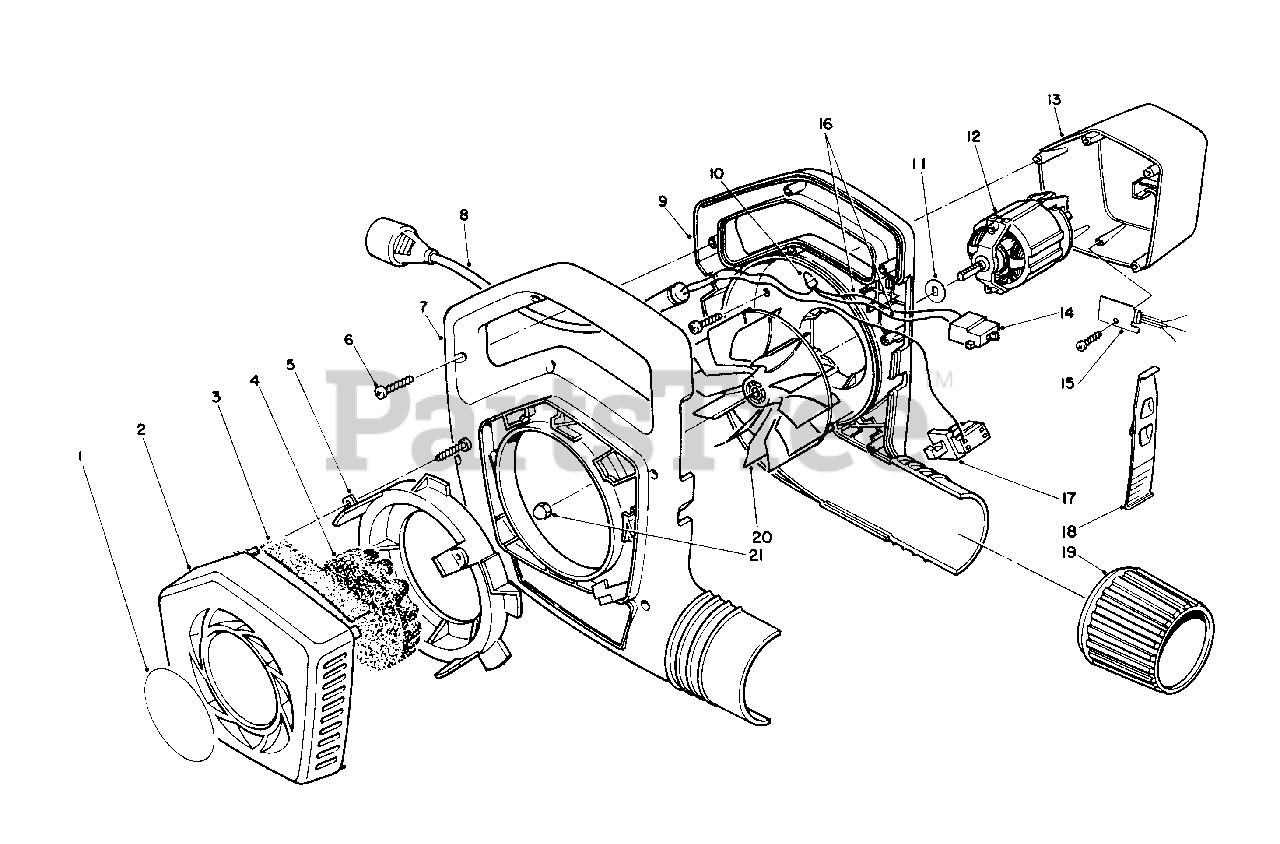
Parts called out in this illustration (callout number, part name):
1	Decal-Cover
2	Cover-Intake
3	Foam-Top
4	Foam-Center
5	Ring-Coupling
6	Screw-Self Tapping
7	Housing-Blower, R.H.
8	Cord-Power Supply
9	Housing-Blower, L.H.
10	Connector-Wire
11	Washer-Impeller
12	Motor-Blower
13	Cover-Motor
14	Switch-2 Speed
15	Diode Assembly
17	Switch-Interlock
18	Switch-Cam, 2 Speed
19	Collar-Output
20	Impeller
21	Nut-Cap, Locking
